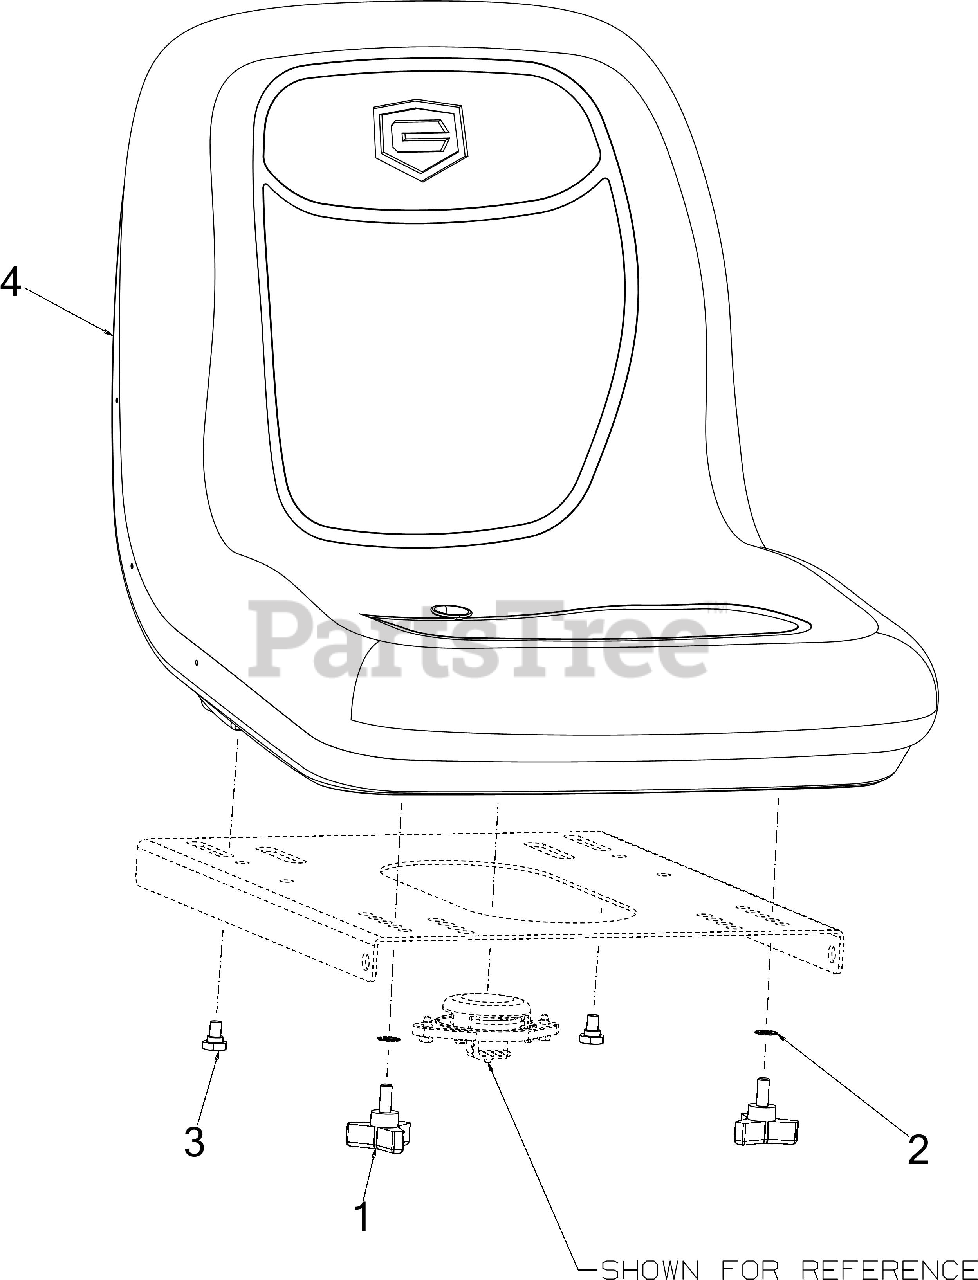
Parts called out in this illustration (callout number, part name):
1	THREE ARM KNOB
2	WASHER
3	SHOULDER SCREW .437
4	SEAT-19" 4 PT MTG
